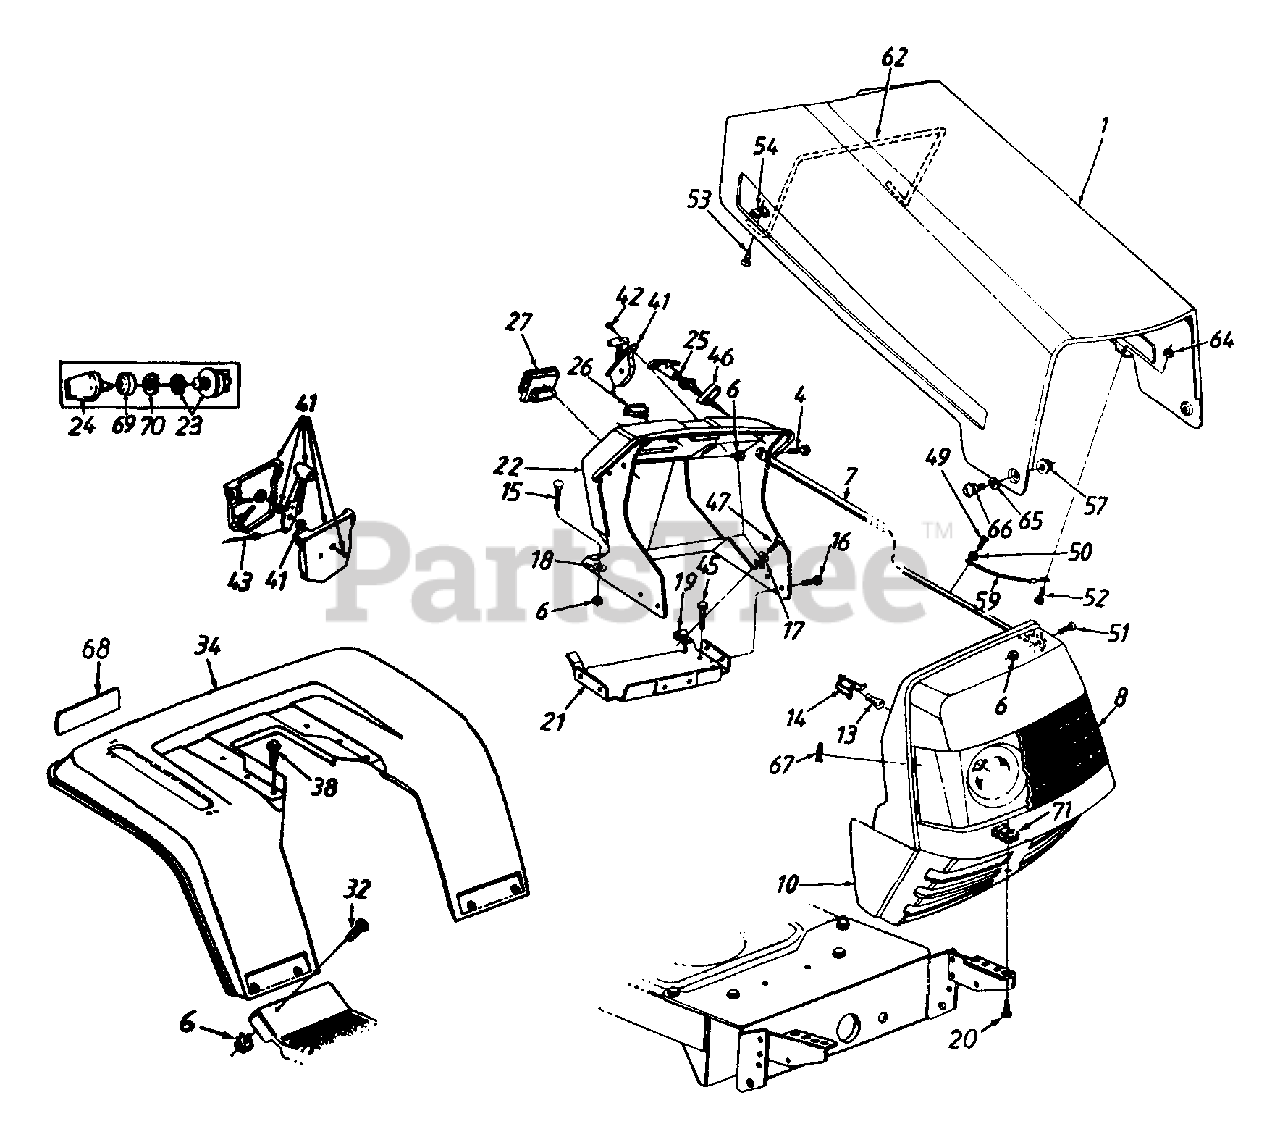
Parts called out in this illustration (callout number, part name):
4	Hex Bolt 1/4-20 x .62" Lg.
6	Hex Sems Nut 1/4-20 Thd.
13	Lamp
14	Socket
15	Carriage Bolt 1/4-20 x .75" Lg.
16	Hex TT-Tap Scr. 1/4-20 x .5" Lg.
17	Fl-Wash. .281" I.D. x .73" O.D.
18	Bolt Retainer 1/4" I.D.
19	Speed Nut 1/4-20 Thd.
20	Hex Bolt 5/16-18 x .75" Lg.
23	Ignition Switch
25	Choke Control 23" Lg.
26	Light Switch
27	Ammeter
32	Truss Mach. Scr. 1/4-20 x .5" Lg.
41	Throttle Box Ass'y.
42	Truss Mach. AB-Tap Scr. #10 x .5" Lg.
43	Throttle Control Wire 18.5" Lg.
45	Hex B-Tap Scr. 5/16-18 x .5" Lg.
46	Choke Retainer
47	Hex TT-Tap Scr. 1/4-20 x .75" Lg.
49	Truss Mach. B-Tap Scr. #10 x .5" Lg.
50	Fl-Wash. .218" I.D. x .62"
51	Pan Hd. Mach. Scr. 1/4-20 x .75"
52	Truss Mach. Scr. #10-24 x .5"
53	Truss Mach. Scr. #10-24 x .75"
54	Speed Nut
57	Lock Nut 1/4-28 Thd.
64	Hex Sems Nut #10-24 Thd.
65	Spr. Wash. .39" I.D. x .62" O.D.
66	Shld. Bolt
67	Hairpin Clip 5/16" Dia.
68	Reflector
69	Ignition Switch Cap
70	Ignition Switch Nut
71	U-Nut 5/16-18 Thd.
